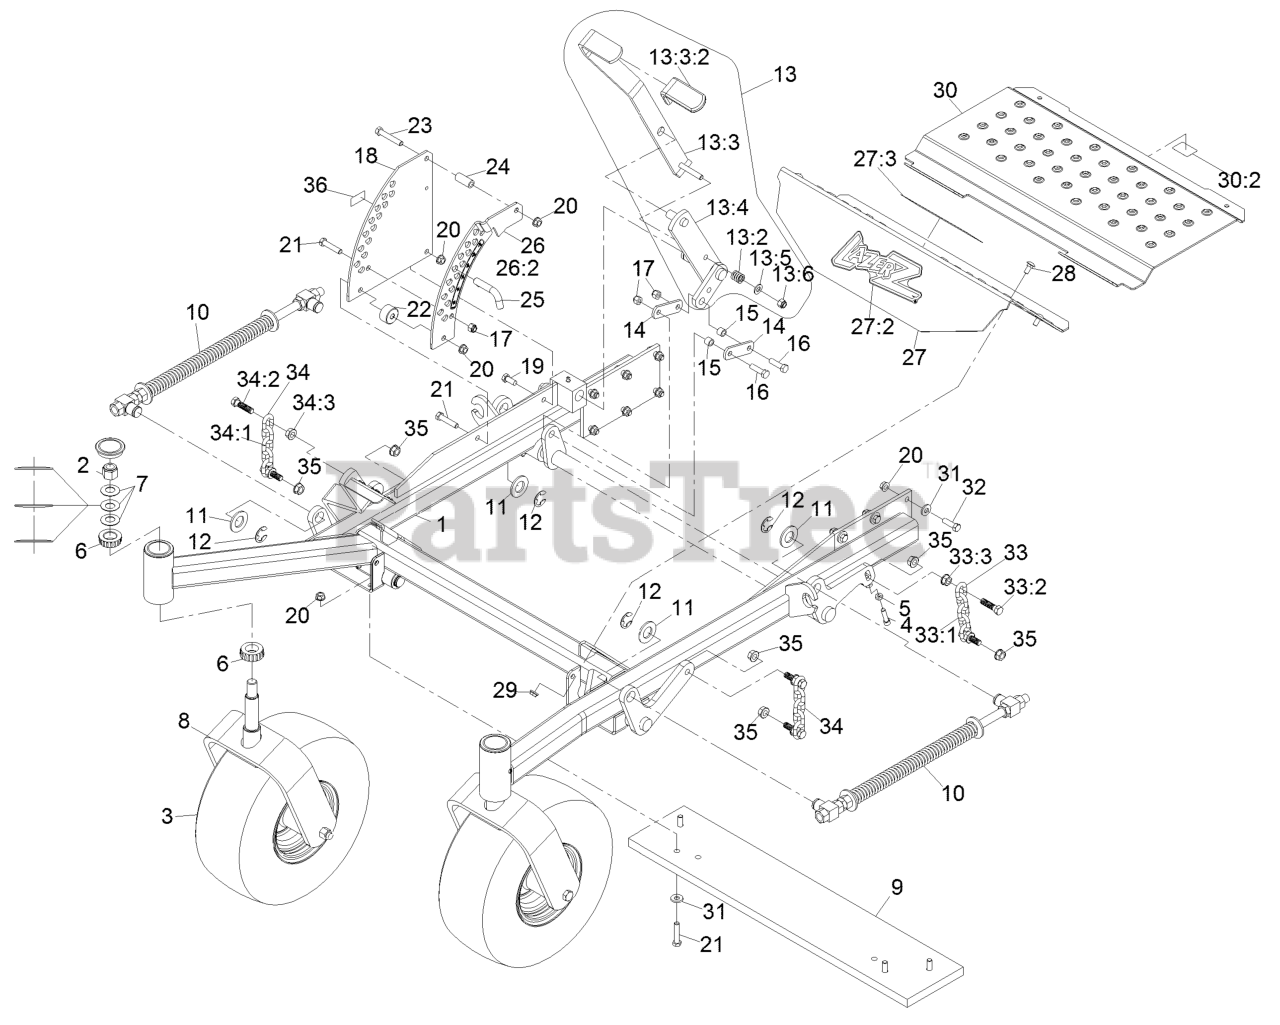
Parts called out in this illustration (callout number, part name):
1	ASM-Frt Frm 60Rd
2	NUT-LOCK, NI
3	ASM-WHL AND TIRE
4	SCREW-HSH
5	NUT-JAM
6	Cone-Bearing Tapered Roller
7	WASHER-BELLVILLE
8	WLD-CASTER FORK 15
9	BAR,WEIGHT 38.1#
10	FRONT FRAME SPRING ASM
11	WASHER-FLAT
12	RING-RETAINING, EXT
13	ASM,Deck Lift Handle
13:2	SPRING-COMPRESSION
13:3	LIFT LEVER/GRIP ASM
13:3:2	GRIP-LEVER, LIFT
13:4	WLD,ARM DECK LIFT
13:5	WASHER-FLAT
13:6	NUT-LOCK, NI
14	ARM-LIFT, DECK
15	BUSHING
16	SCREW-HH
17	NUT-LOCK, NI
18	PLATE-DECK LIFT NOTCHED O
19	SCREW-HH
20	NUT-HHF, WHIZ
21	SCREW-HH
22	Stop, Deck Height
23	SCREW-HH
24	BUSHING-LEVER, LIFT
25	PIN-HOC
26	PLATE-LIFT, DECK W/DECAL
26:2	DECAL-HEIGHT OF CUT
27	ASM, FLOORPAN FRONT W/DEC
27:2	DECAL,LAZER MODEL
27:3	DECAL-WARNING, SLOPE
28	BOLT-CARR
30	ASM, FLOORPAN LIFTOUT W/D
30:2	Decal-Guard
31	WASHER-BELLEVILLE
32	SCREW-HH
33	DECK CHAIN ASM
33:1	CHAIN-LIFT, DECK
33:2	SCREW-HH
34	DECK CHAIN ASM
34:1	CHAIN-LIFT, DECK
34:2	SCREW-HH
36	Decal-Patent Ttco.Com
